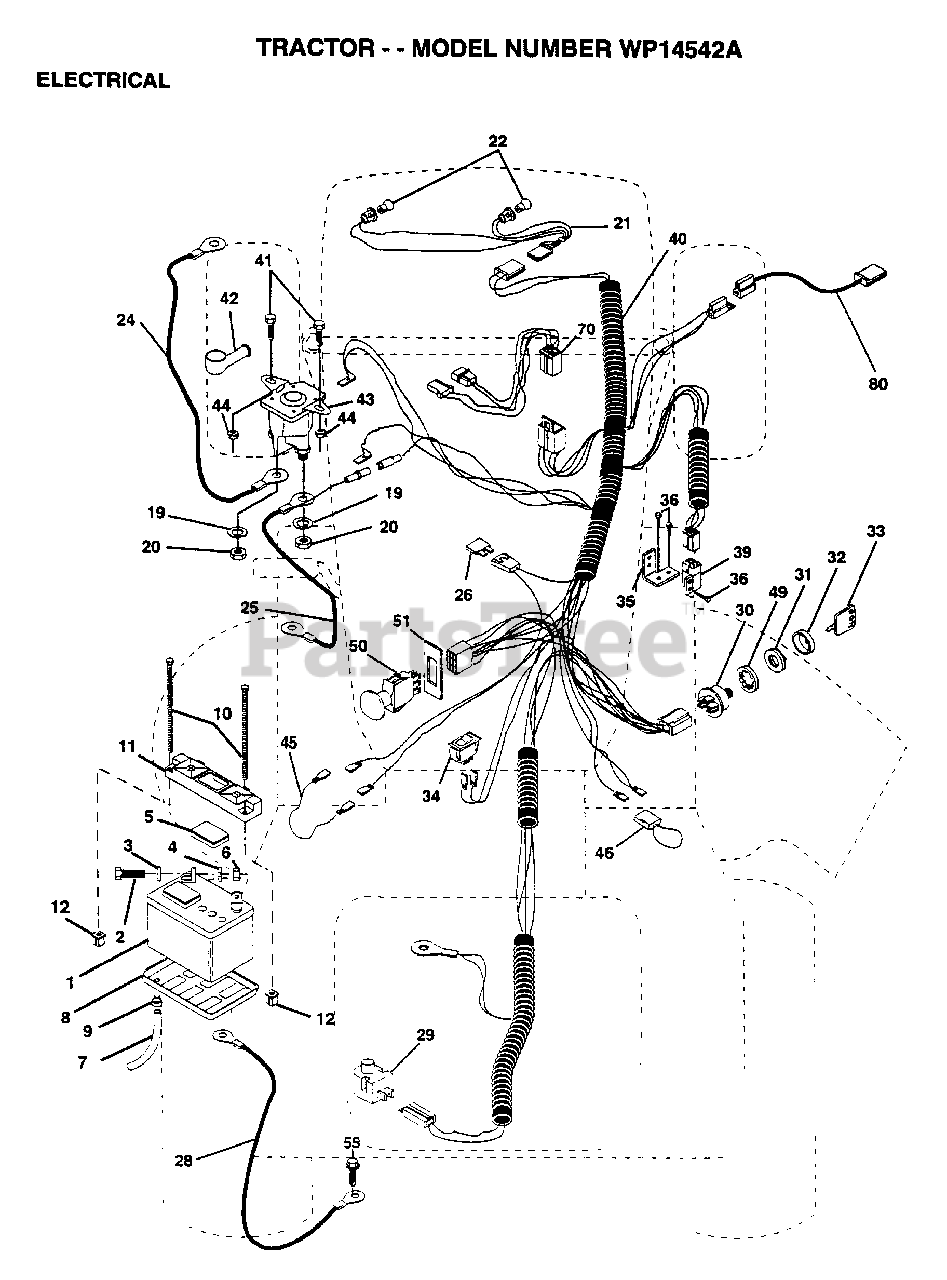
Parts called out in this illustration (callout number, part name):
2	BOLT LT
3	WASHER
4	LOCKWASHER
5	"CAP,BATTERY "
7	"DRAIN TU T, BATT"
8	"TRAY T, BATTERY"
9	HOSE CLAMP T
20	NUT
21	"HARNESS,LIGHT SOC"
22	HEADLAMP BULB
24	CABLE.BTRY.6GA.RD
25	CABLE.6GA.22W/16W
26	FUSE HYT
28	CABLE.GRND.6GA.21
29	SWITCH SEAT
32	COVER KEY SWITCH
33	KEY MLD GEN DELTA
34	SWITCH LT
35	BRACKET LT
36	SCREW
38	BRACKET SWITCH IN
39	SWITCH INTERLOCKT
40	HARNESS.ING.ELEC.
41	BOLT.HX.1/4-20
44	NUT
45	ADAPTER AMMETER
46	PROTECTION LOOP
49	LOCKWASHER
51	RING RETAIN PTO
55	SCREW LT
70	HARNESS.ENG.DUAL
80	HARNESS.CLUT.EVX.
